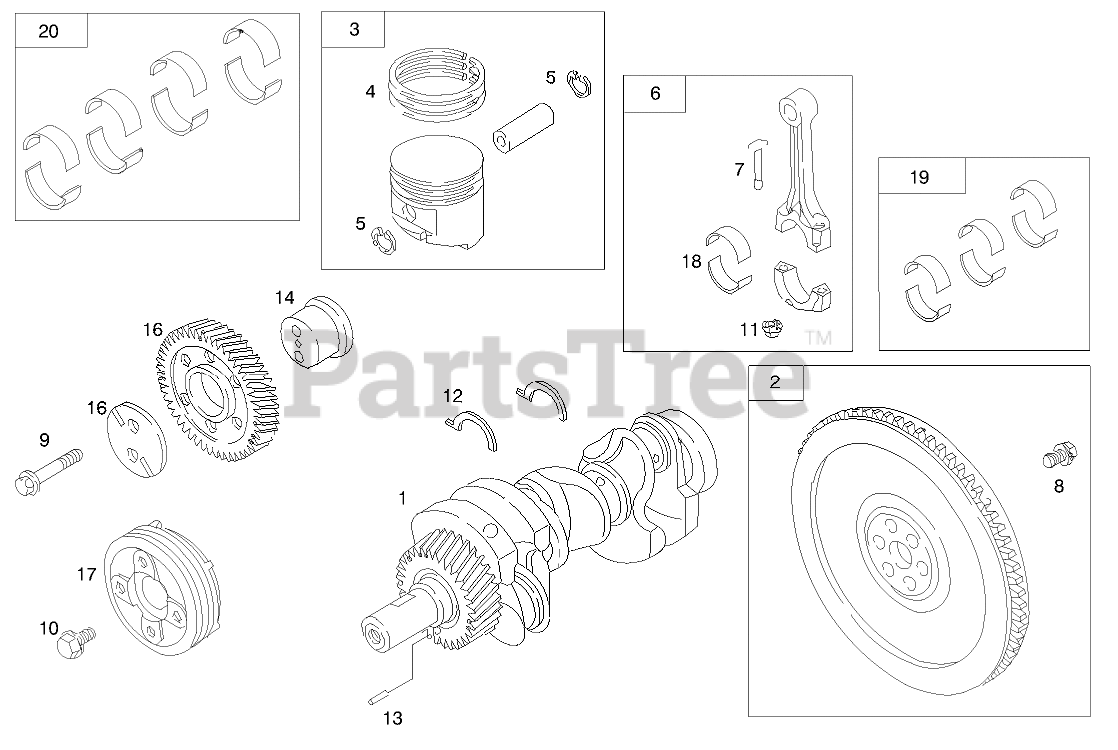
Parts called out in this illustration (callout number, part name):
1	CRANKSHAFT
1	HEAD-CYLINDER
2	FLYWHEEL
3	PISTON ASM
4	RING SET
5	LOCK-PIN, PISTON
6	ROD-CONNECTING
7	SCREW-ROD, CONNECTING
8	SCREW-HEX
8	SWITCH-TEMPERATURE, WATER
9	SCREW-HEX
9	GASKET-SET
10	SCREW-HEX
11	NUT-HEX
12	WASHER-THRUST
13	PIN-LOCATING
14	Gear-Drive
14	KIT-VALVE OVERHAUL
15	SHAFT-GEAR
16	PLATE-GEAR, IDLER
17	Pulley-Crankshaft
18	BEARING-ROD
19	SET-BEARING, ROD
20	SET-BEARING, MAIN (SET OF 8)
